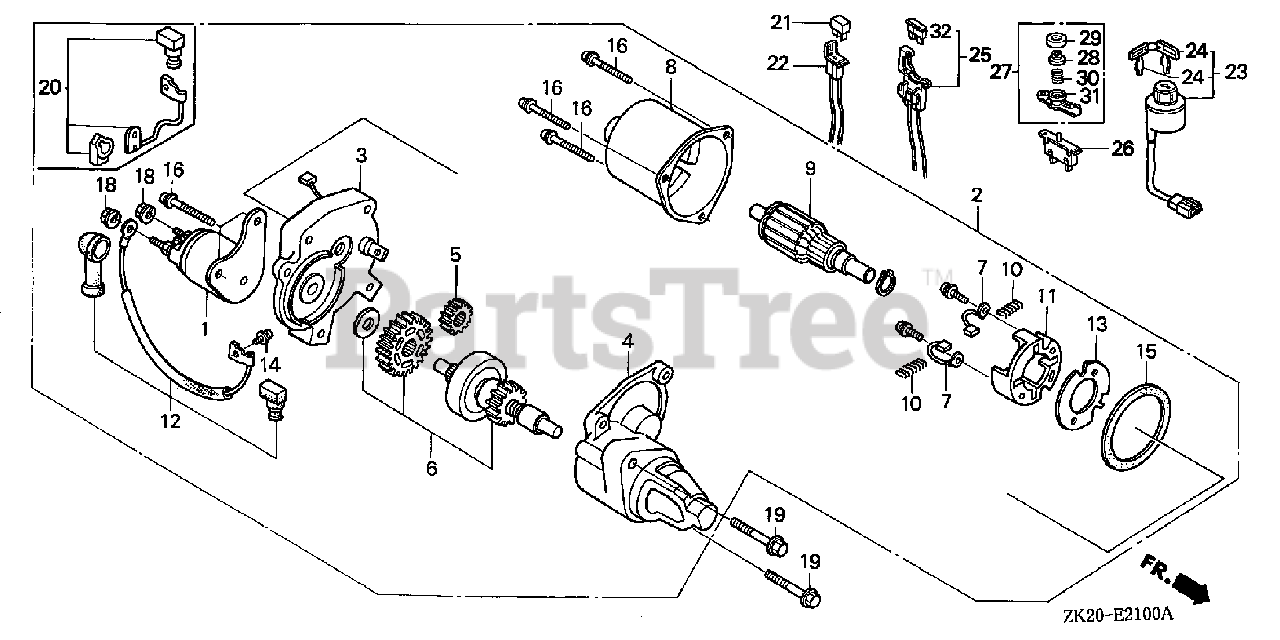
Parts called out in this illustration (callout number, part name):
1	CONTACTOR ASSY.
2	MOTOR UNIT, STARTER
3	BRACKET, CENTER
4	BRACKET, FR.
5	GEAR, DRIVE PINION
6	CLUTCH, OVERRUNNING
7	BRUSH
8	YOKE
9	ARMATURE
10	SPRING, BRUSH RETURN
11	HOLDER, BRUSH
12	WIRE, WATER COVER
13	INSULATOR
14	SCREW-WASHER (4X6)
15	GASKET
16	SCREW-WASHER (5X3)
18	NUT-WASHER (6MM)
19	BOLT, FLANGE (8X40)
